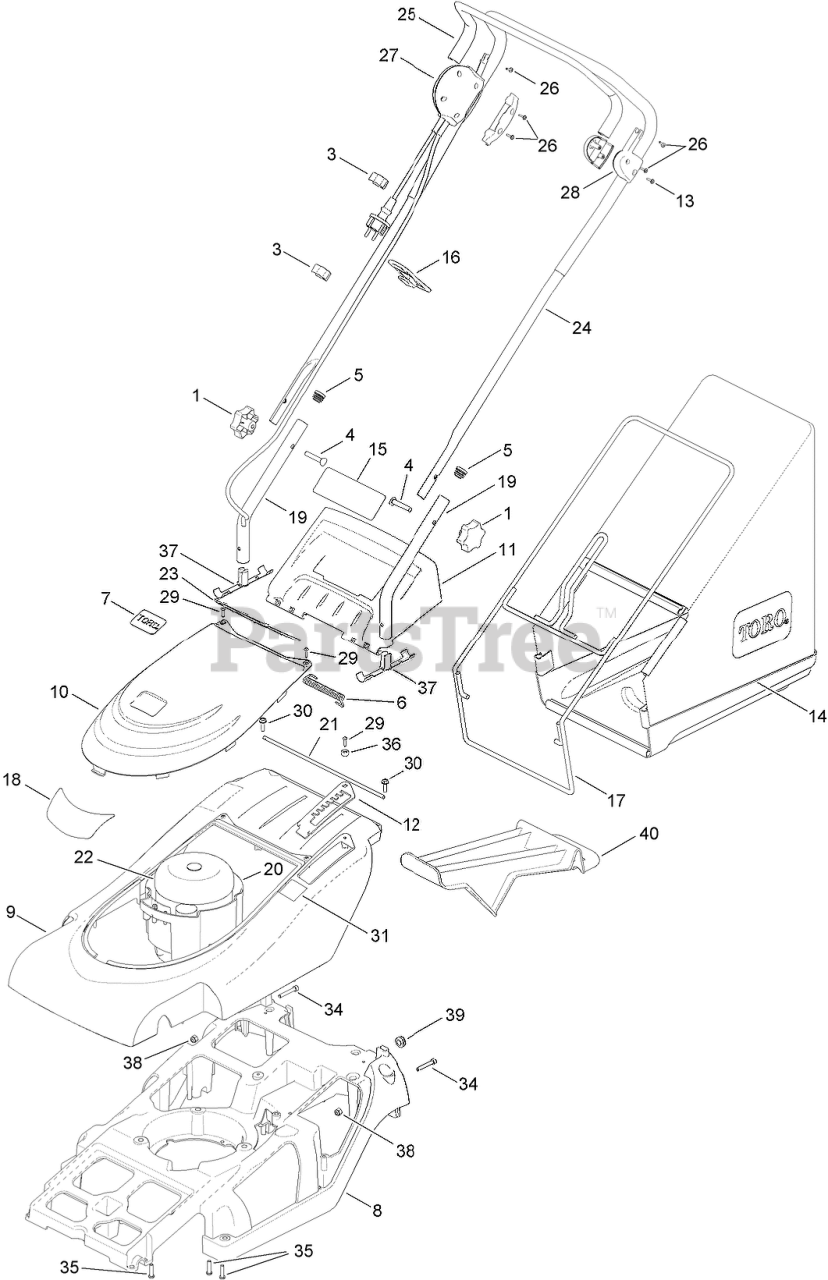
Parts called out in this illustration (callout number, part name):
1	KNOB-HANDLEBAR
3	GUIDE-CABLE
4	BOLT-HANDLEBAR
5	PLUG-TUBE
6	SPRING-DEFLECTOR
7	DECAL-TORO
8	CHASSIS
9	TOP-COVER
10	COVER-MOTOR
11	MOULDING-DEFLECTOR, REAR
12	PLATE-HOC
13	SCREW-PPH
14	GRASSBAG
15	DECAL-SAFETY, ELECTRIC
16	CLEAT-CABLE
17	FRAME-GRASSBAG
19	HANDLEBARS-LOWER
20	MOULDING-MOUNT, ELECTRIC MOTOR
21	BAR-HINGE
22	MOTOR-INDUCTION, 1.5KW
23	VENT MESH ASM
24	HANDLEBARS-ELECTRIC
25	ARM-BAIL
27	SWITCH AND LEAD ASM
28	MOUNT BAIL ARM ASM
30	SCREW-TAPTITE
31	DECAL-HOC
34	SCREW-SOCKET
36	CUP-SCREW, ELECTRIC
37	PLUG-HANDLEBAR
38	NUT-NYLOC
39	GROMMET-RUBBER
40	PLUG-MULCHING
